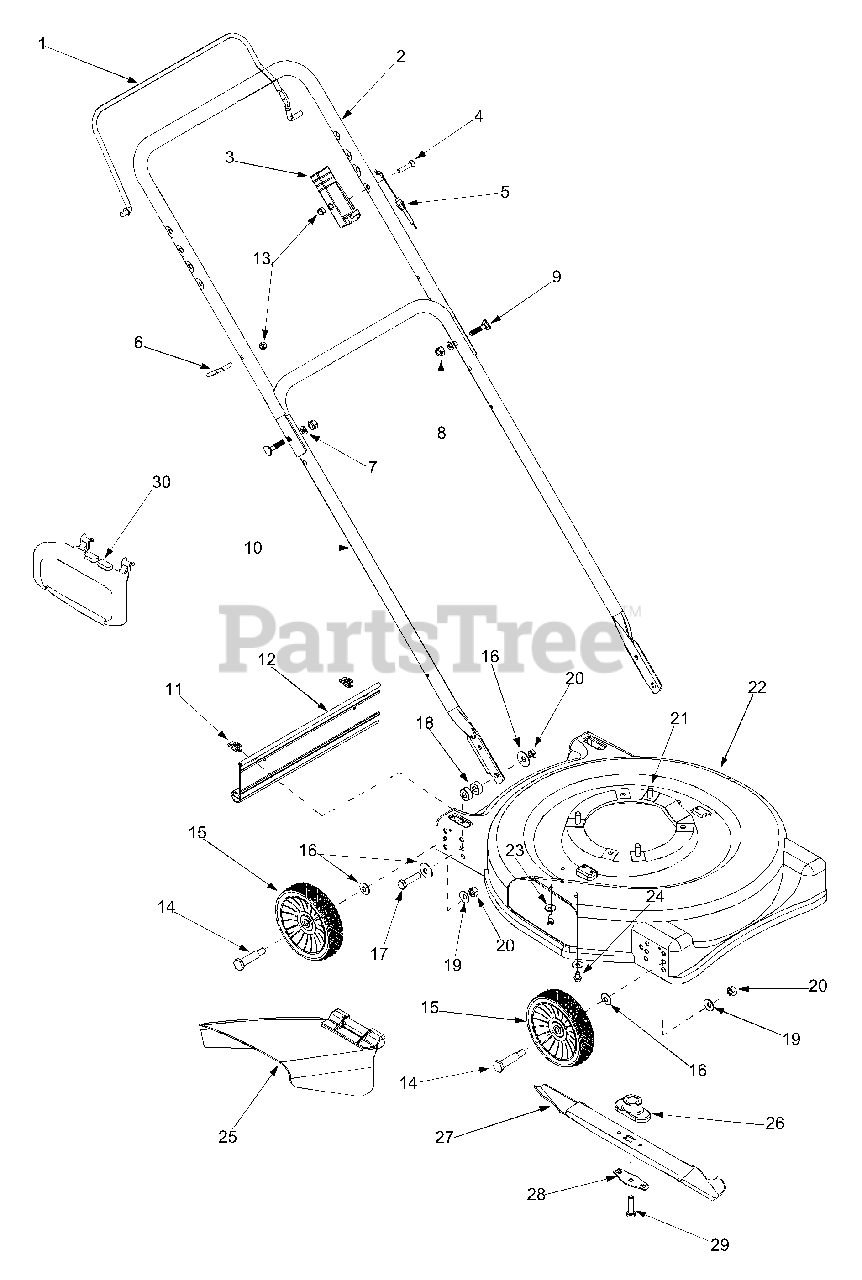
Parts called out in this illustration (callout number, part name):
4	Oval C-Sunk Screw
5	Control Cable
6	Rope Guide
7	Lock Washer 5/16"
8	Hex Nut 5/16-18
9	Carriage Bolt 5/16-18 x 1"
11	Hinge Clip
12	Rear Trail Shield
13	Hex Lock Nut
14	Axle Bolt
15	Wheel Assembly
16	Bell Washer.380 ID x .88"
17	Hex Bolt 3/8-24 x 1.5
18	Spacer .391" ID x .850" OD
19	Bell Washer.39 ID x 1.13 OD
20	Hex Nut 3/8-16
21	Hex Washer Screw 3/8-16 x 1"
24	Hex Washer Screw 1/4-20 x.5"
25	Chute Deflector Assembly
26	Blade Adapter
27	Blade
28	Bell Blade Support
29	Hex Bolt 3/8-24 x 1.5"
30	Snap Mulching Plug (If Equipped)
